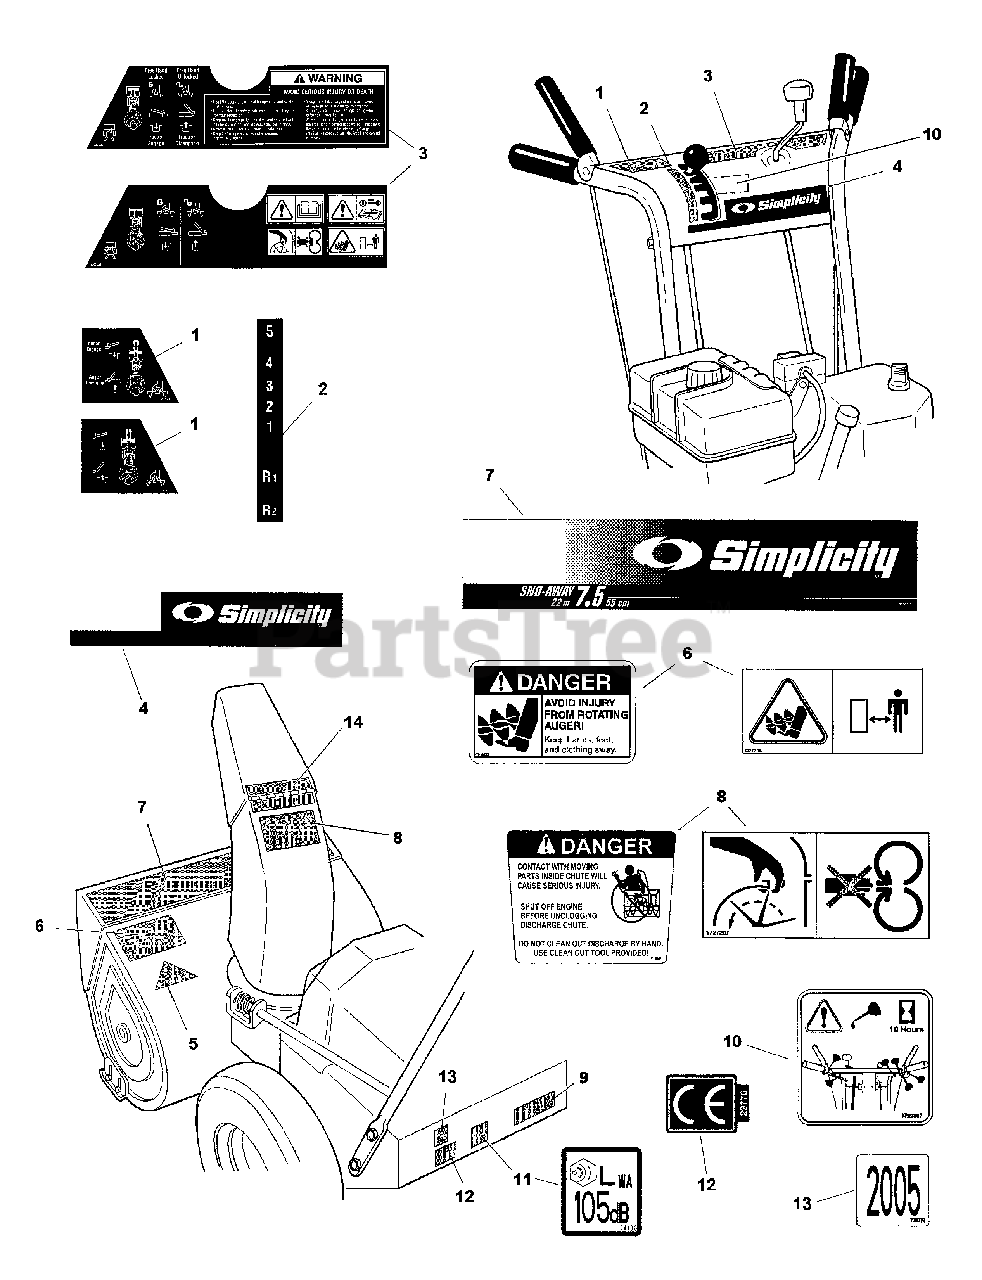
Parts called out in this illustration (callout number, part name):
1	DECAL, Dashboard- RH
1	DECAL, Dashboard- RH- Euro
2	DECAL, Shift Pattern
3	DECAL, Dashboard- LH
3	DECAL, Dashboard- LH- Euro
4	DECAL, Dash Front - Simplicity
5	DECAL, OPEI (Not Serviced)
6	DECAL - Danger, Auger
6	DECAL, CE- Auger Warning
7	DECAL, Stripe- Simplicity (7.5hp, 22")
8	DECAL, Danger, Chute/Deflector
8	DECAL, Chute Warning
9	I.D. Tag (Not Serviced)
10	DECAL, Lube- Controls
11	DECAL, Sound 105
12	DECAL, Euro Community
13	DECAL, 2005 Year of Manufacture
14	DECAL- Hinge (Orange)
